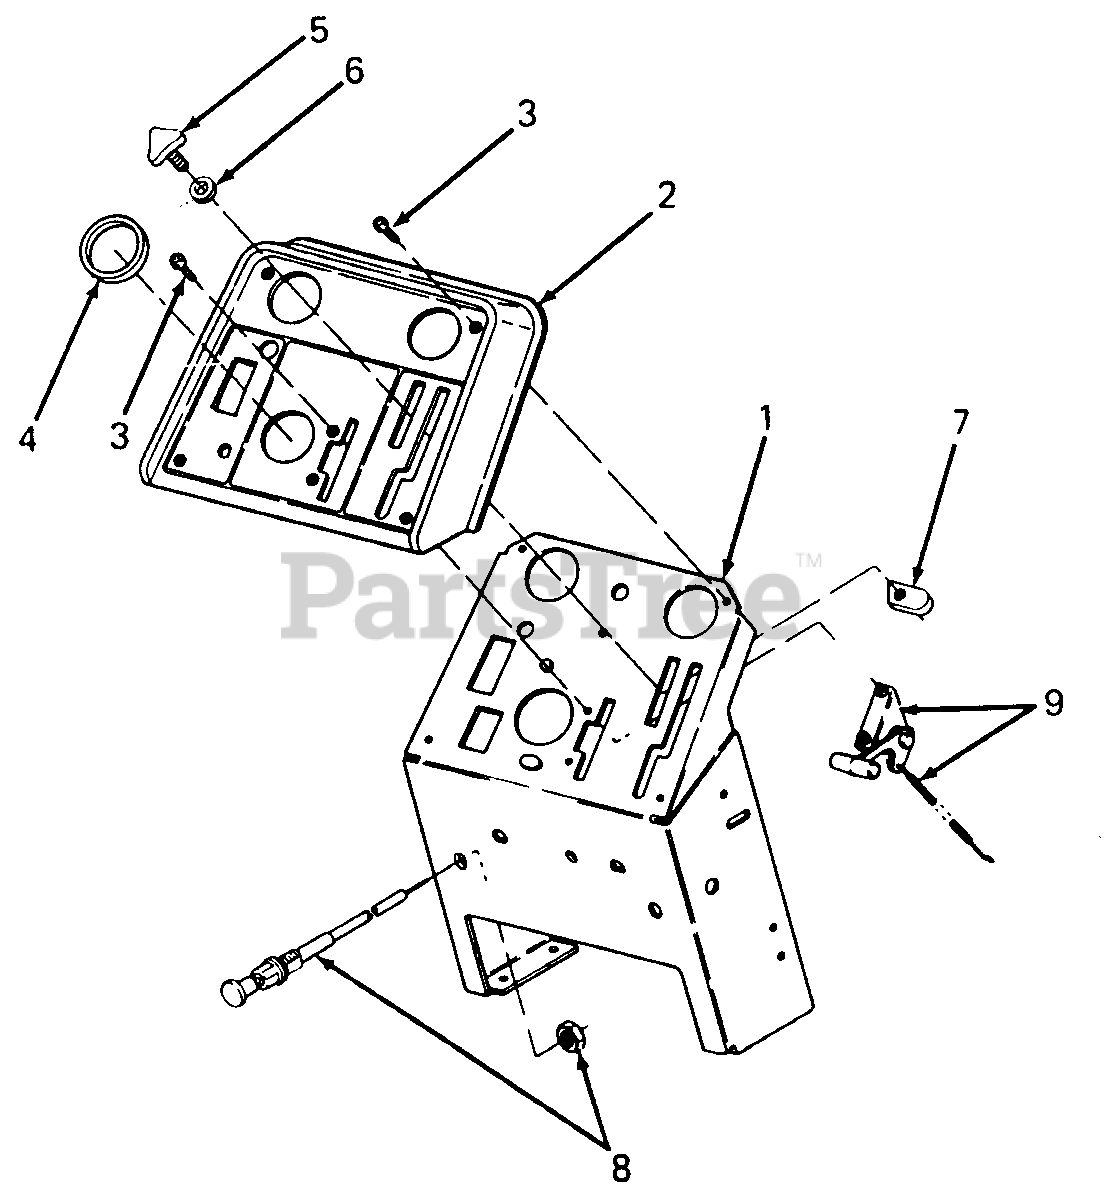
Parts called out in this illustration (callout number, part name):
2	Panel, Instrument
3	Screw, Pan Hd Cutting, #10-24 X .75 Lg
4	Grommet, Instrument Panel
6	Washer, Flat, .266 X .625 X .035 Thk
7	Stop, Detent Handle
8	Choke Cable w/Nut
9	Control, Throttle
